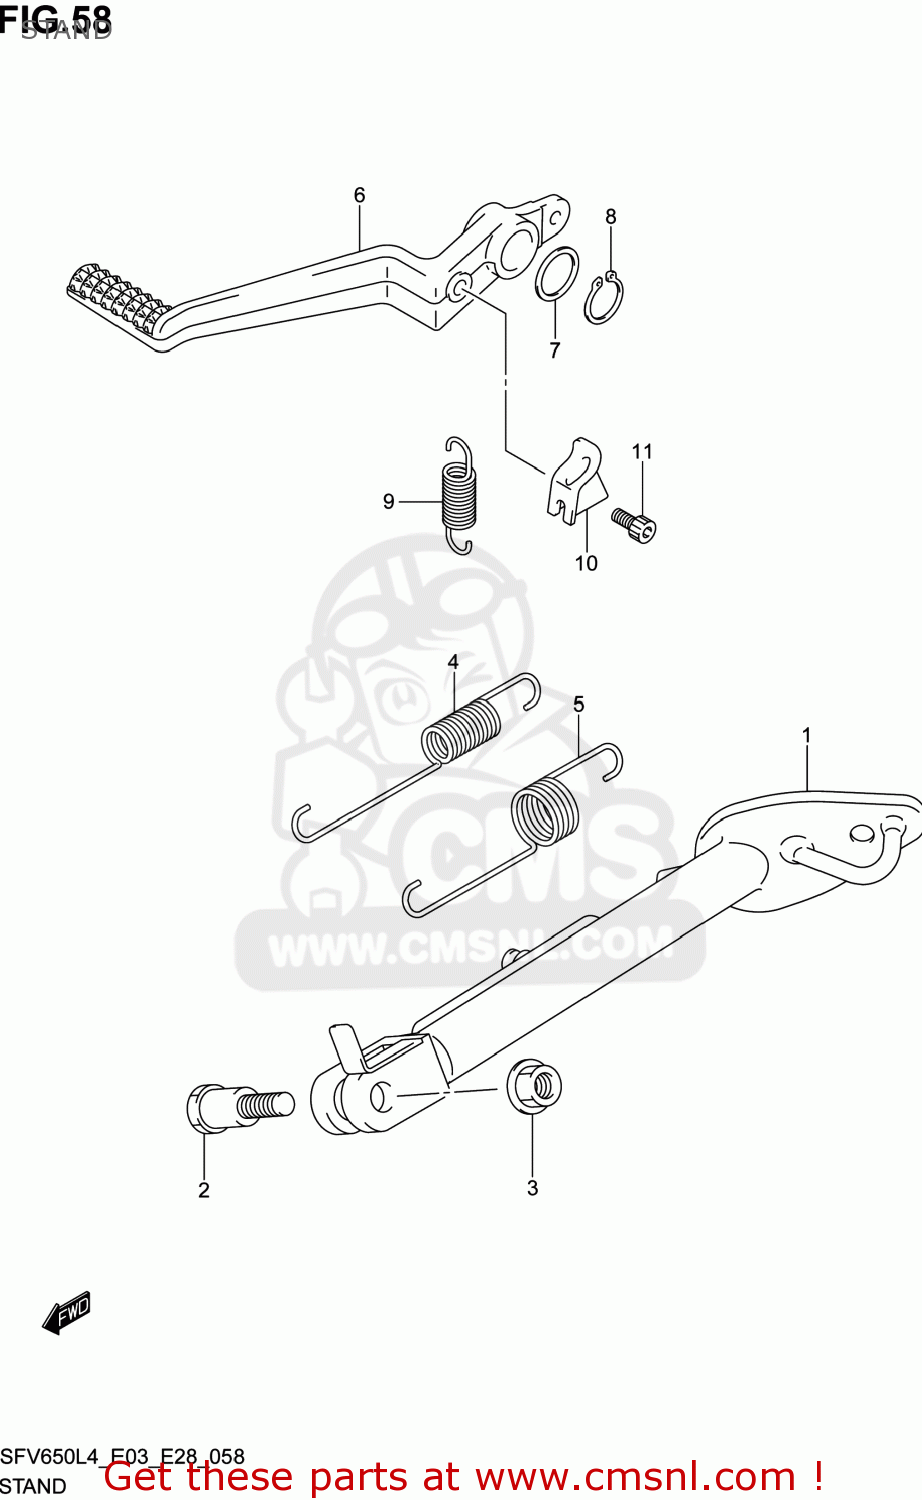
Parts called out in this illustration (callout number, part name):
1	STAND,PROP
2	BOLT(10X21)
3	NUT
4	SPRING
5	SPRING
6	PEDAL,BRAKE
7	WASHER(18X24X1)
8	CIRCLIP
9	SPRING
10	BRACKET,RETURN SPRING
11	BOLT
